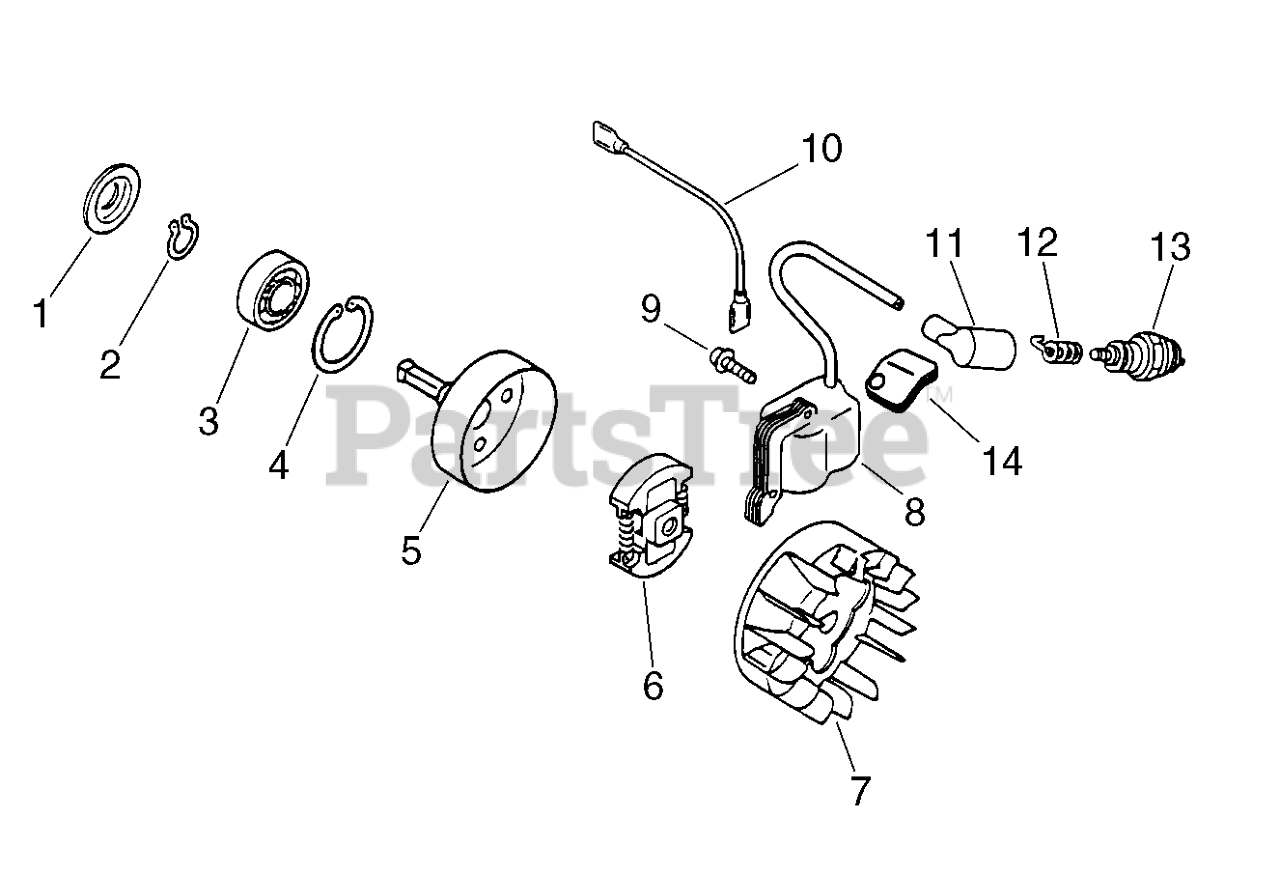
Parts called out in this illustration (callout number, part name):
1	STOPPER, PIPE
2	RING, SNAP 12
3	BEARING, BALL 6201-ZZ
4	RING, SNAP Ø32
5	DRUM, CLUTCH
7	FLYWHEEL
8	COIL, IGNITION
9	SCREW 4×22
10	LEAD
11	CAP, SPARK PLUG
12	TERMINAL, SPARK PLUG
13	SPARK PLUG - RCJ7Y
